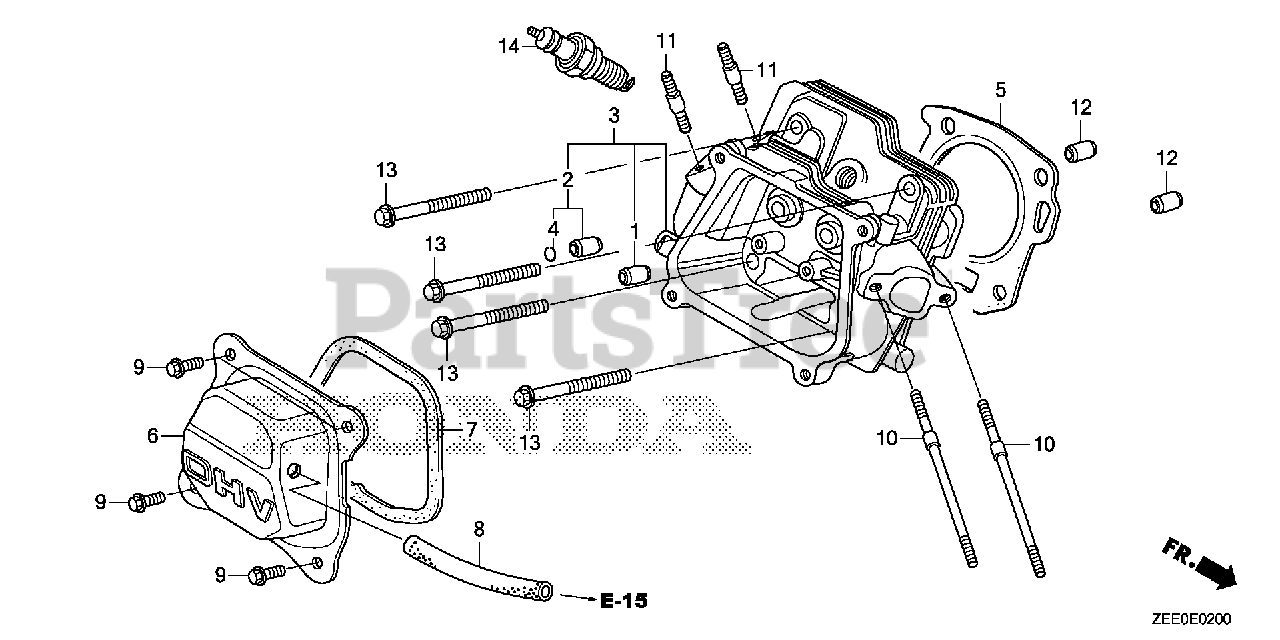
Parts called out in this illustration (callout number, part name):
1	GUIDE, VALVE (OVER SIZE) Use from Engine SN 6324986.
2	GUIDE, EX. VALVE (OS)
3	CYLINDER HEAD
4	CLIP, VALVE GUIDE Use from Engine SN 1231803.
5	GASKET, CYLINDER HEAD (NIPPON LEAKLESS)
6	COVER, HEAD
7	GASKET, HEAD COVER (NINGBO SIL GASKET)
7	GASKET, CYLINDER HEAD COVER
8	TUBE, BREATHER
9	BOLT, FLANGE (6X12) (CT200)
10	BOLT, STUD (6X112)
11	BOLT, STUD (8X32)
12	PIN A, DOWEL (10X16)
13	BOLT, FLANGE (8X60)
14	SPARK PLUG (BPR5ES) (NGK)
14	SPARK PLUG (W16EPR-U) (DENSO)
14	SPARK PLUG (BPR6ES) (NGK)
14	SPARK PLUG (W20EPR-U) (DENSO)
